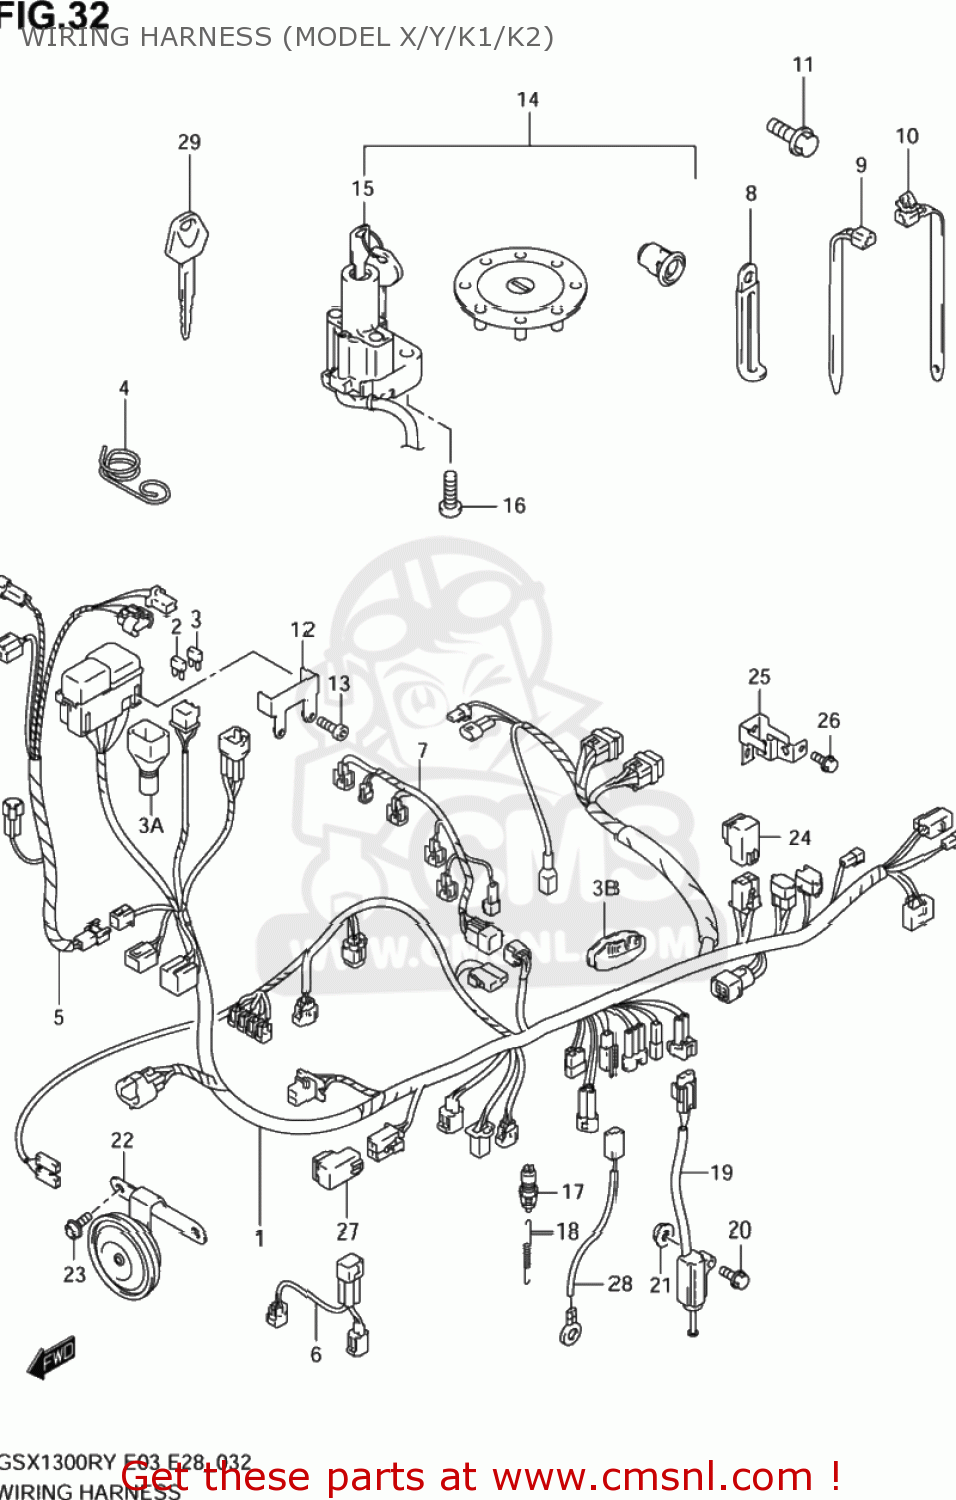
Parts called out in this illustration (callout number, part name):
1	HARNESS,WIRING
2	FUSE(10A)
3	FUSE(15A)
3A	COVER,SPEEDOMETER COUPLER
3B	PROTECTOR,WIRING HARNESS
4	GUIDE,WIRING HARNESS
5	HARNESS,WIRING NO.2
6	WIRE,SENSOR LEAD
7	WIRE,INJECTOR LEAD
8	CLAMP(L:65)
9	CLAMP(L:125)
10	CLAMP
11	BOLT
12	BRACKET,FUSE BOX
13	BOLT
14	LOCK SET
15	LOCK ASSY,STEERING
16	BOLT(8X20)
17	SWITCH ASSY,STOP LAMP
18	SPRING
19	SWITCH ASSY,SIDE STAND
20	BOLT(8X35)
21	NUT
22	HORN ASSY
23	BOLT
24	RELAY ASSY
25	BRACKET,FUEL PUMP RLY
26	BOLT
27	RELAY ASSY
28	WIRE,OIL PRESSURE SWITCH LEAD
29	KEY,BLANK
